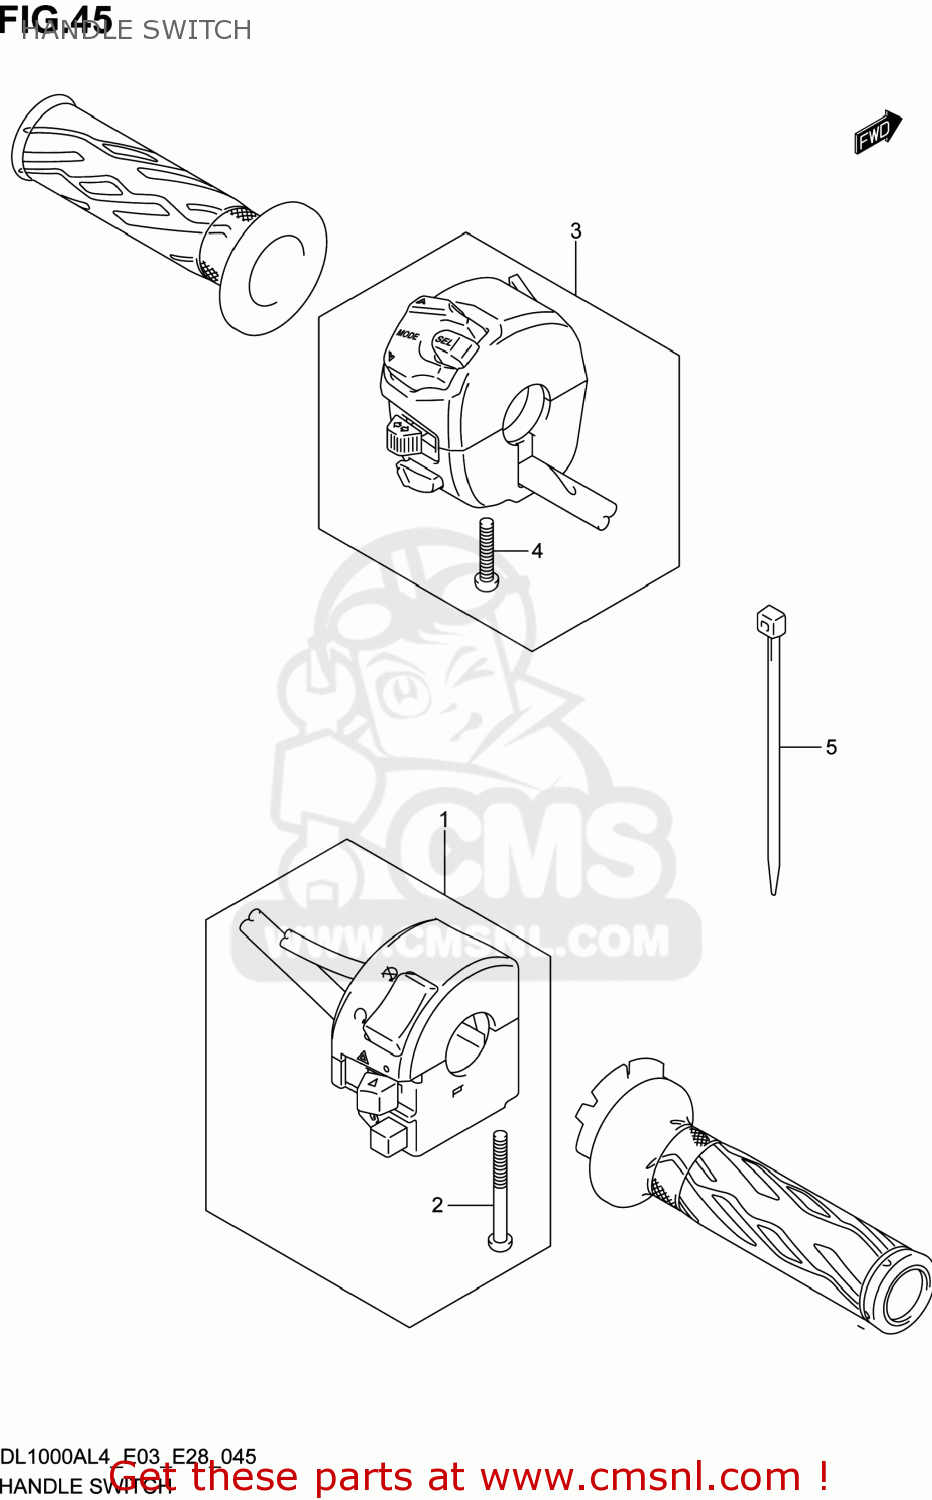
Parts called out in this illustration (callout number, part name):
1	SWITCH ASSY,HANDLE,R
2	SCREW
3	SWITCH ASSY,HANDLE,L
4	SCREW
5	CLAMP(L:145)
